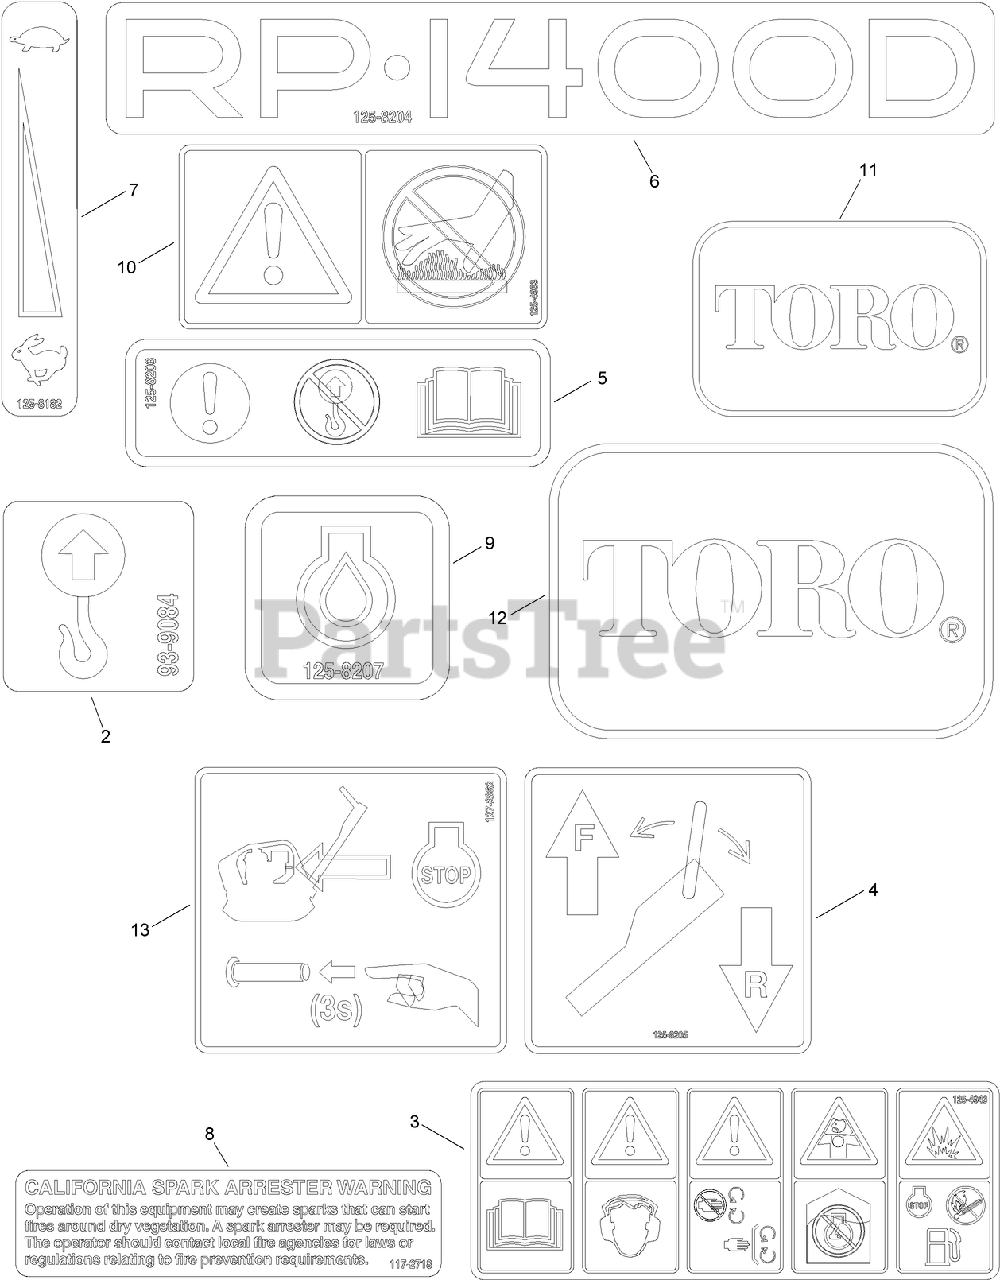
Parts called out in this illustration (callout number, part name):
2	DECAL-POINT, LIFT
3	DECAL-WARNING, PLATE
4	DECAL-OPERATION
5	DECAL-CAUTION
7	DECAL-THROTTLE
8	DECAL-ARRESTER, SPARK
9	DECAL-OIL, ENGINE
10	DECAL-SURFACE, HOT
11	DECAL
13	DECAL-STOP, ENGINE
